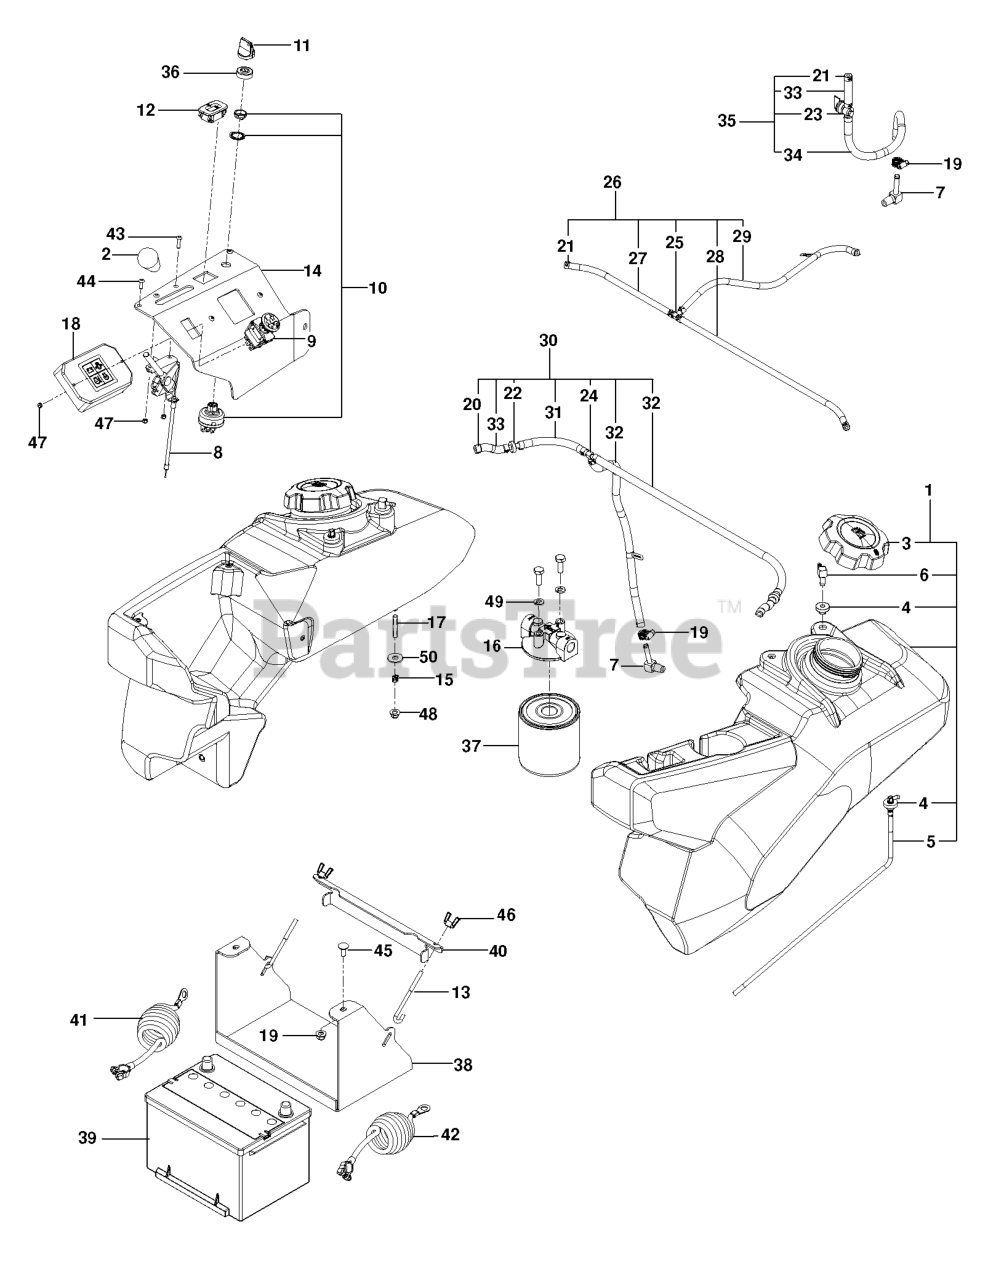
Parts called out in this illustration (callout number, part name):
1	FUEL TANK LT DIESEL
2	KNOB - SHIFT
3	CAP, DIESEL FUEL
4	RUBBER GROMMET
5	FITTING, FUEL
6	FITTING, RETURN, 90
7	FITTING, FUEL, 90
8	CABLE, THROTTLE, DIESEL
9	SWITCH, PTO 10 AMP
10	SWITCH, IGNITION, INDAK
11	KEY, IGNITION
12	HOUR METER
13	HOOK, "J"
14	PANEL, CONTROL, DIESEL-GRAY
16	HEAD, FUEL FILTER
17	STUD, 5/16C
18	MODULE, CONTROL
19	CLAMP, WORM GEAR, NO. 4
20	CLAMP, HOSE
21	HOSE CLAMP
22	VALVE, CHECK, .25
23	FUEL VALVE
24	TEE, FUEL LINE, .25
25	TEE, FUEL LINE 3/16"
26	ASSEMBLY, FUEL LINE, RETURN
27	HOSE, FUEL, 3/16" X 9-1/2"
28	HOSE, FUEL, 3/16" X 17-1/4"
29	HOSE, FUEL, 3/16" X 18-1/2"
30	ASSEMBLY, FUEL LINE
31	FUEL LINE 5"
32	HOSE, FUEL 1/4" X 21"
33	FUEL LINE 3"
34	FUEL LINE 14"
35	LINE, FUEL ASSEMBLY
36	CAP IGNITION NUT
37	FILTER, FUEL
38	BOX, BATTERY, BLK
39	BATTERY, 500 CCA
40	BRACKET, BATTERY MOUNT
41	CABLE, POSITIVE
42	CABLE, NEGATIVE
43	SCR #10-24 X .75 SKT HD BLK
44	SCR #10-24 X 3/8 SKT HD BLK OX
45	BOLT 5/16C X 3/4" CARRIAGE
46	WING NUT 1/4
47	NUT 10-24 NYLOC
48	5/16-18 NYLOC FLANGE NUT
49	LOCKWASHER 1/4"
50	FLAT WASHER 5/16 SAE
